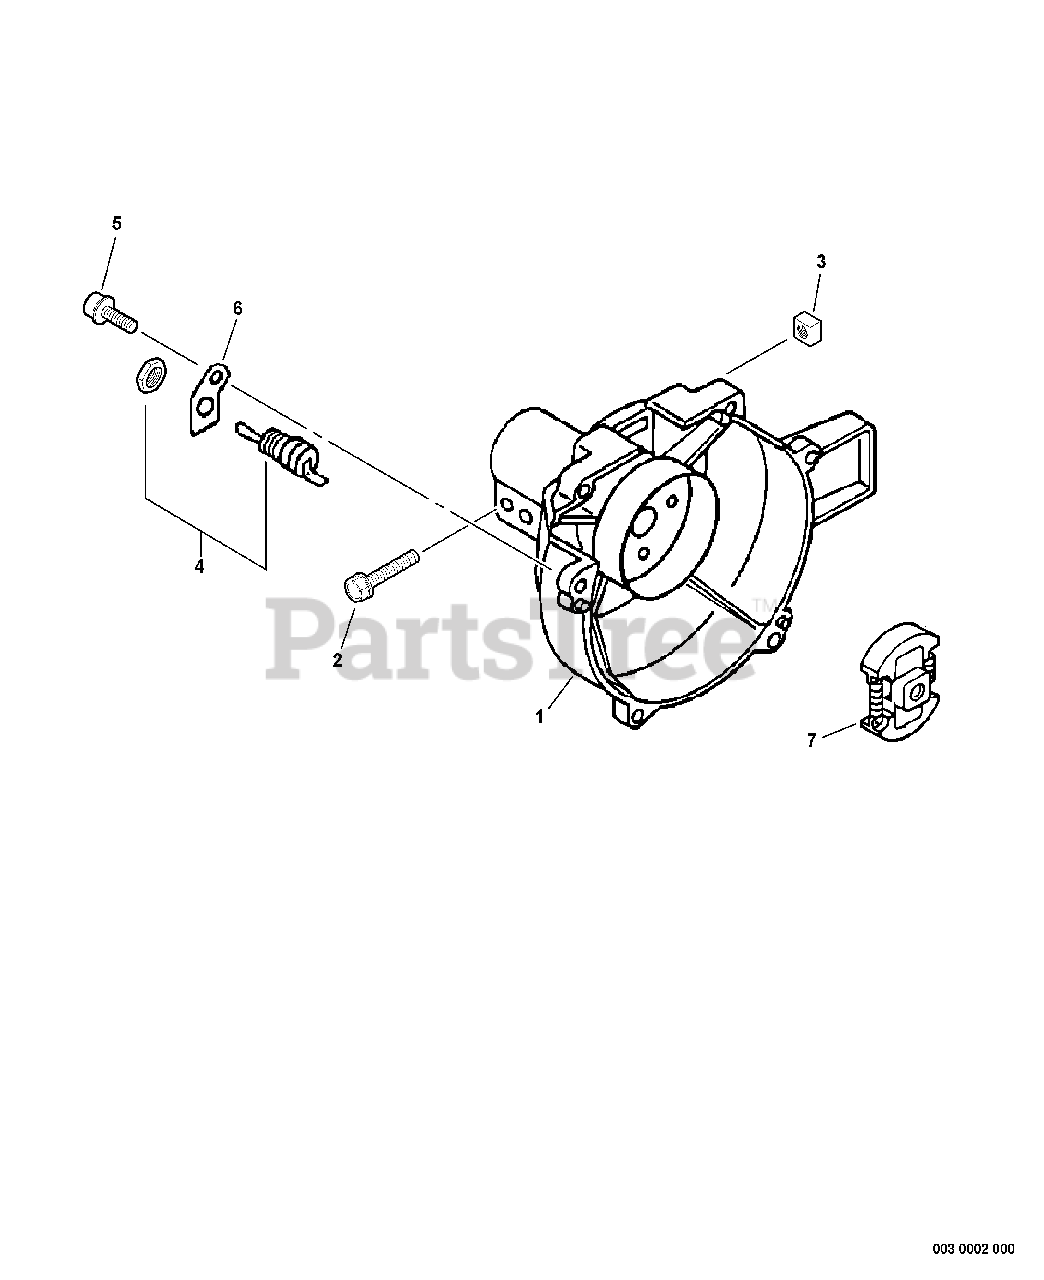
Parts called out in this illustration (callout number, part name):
1	FAN CASE ASSY
2	BOLT - 5X28
3	NUT - 5 -- SQUARE
4	IGNITION SWITCH ASSY
5	SCREW - 4X18
6	BRACKET, SWITCH
7	CLUTCH ASSY
